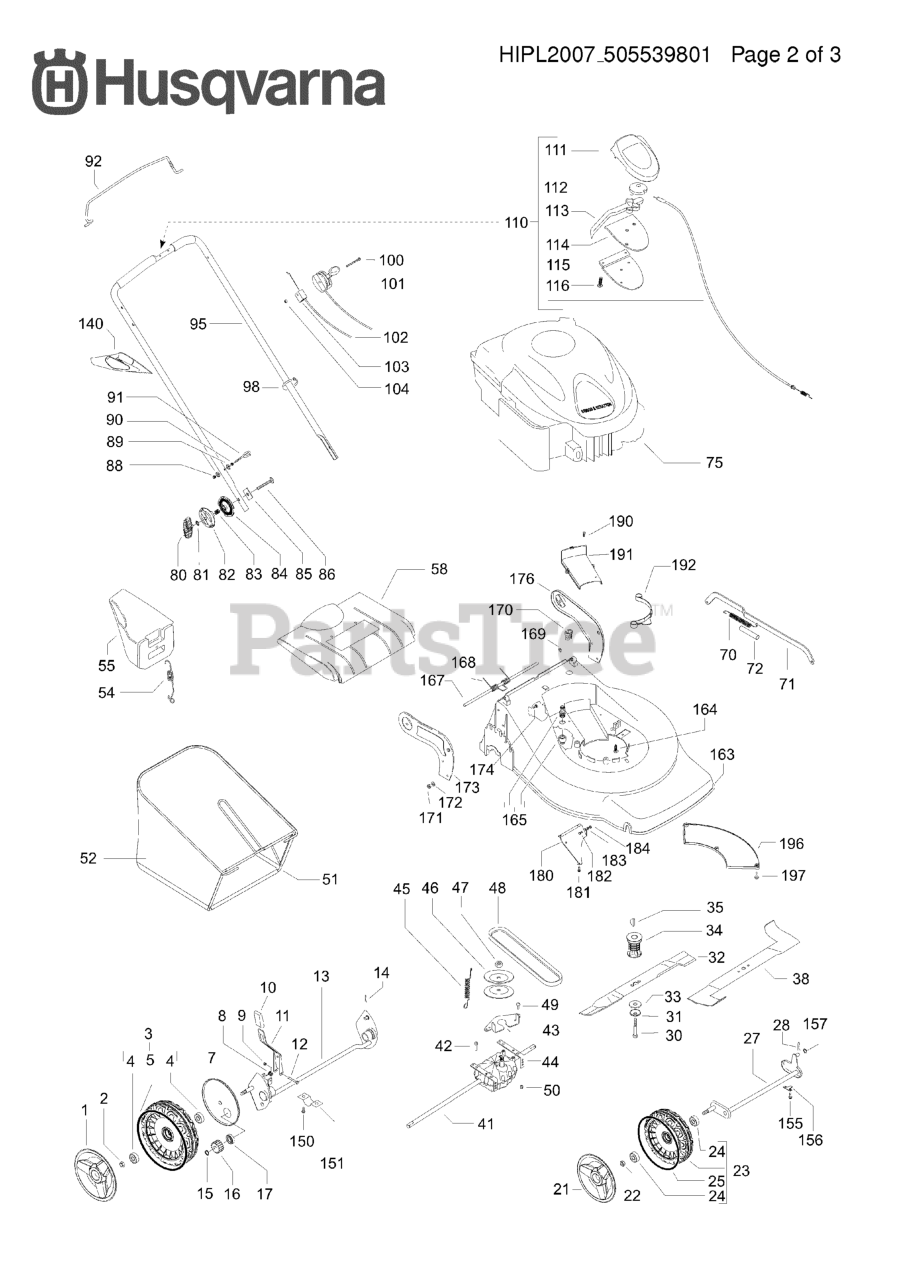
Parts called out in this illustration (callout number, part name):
2	VALVE STEM LT
3	RIM ASM 6" FRONT SILVER
4	TUBE.5.3/4.5/6
5	TIRE HEAVY DUTY
6	FITTING LT
7	BEARING T
8	CAP, AXLE BLK
9	TIRE.TS.20X10-8
10	TUBE
11	RIM ASM 8" REAR SILVER
